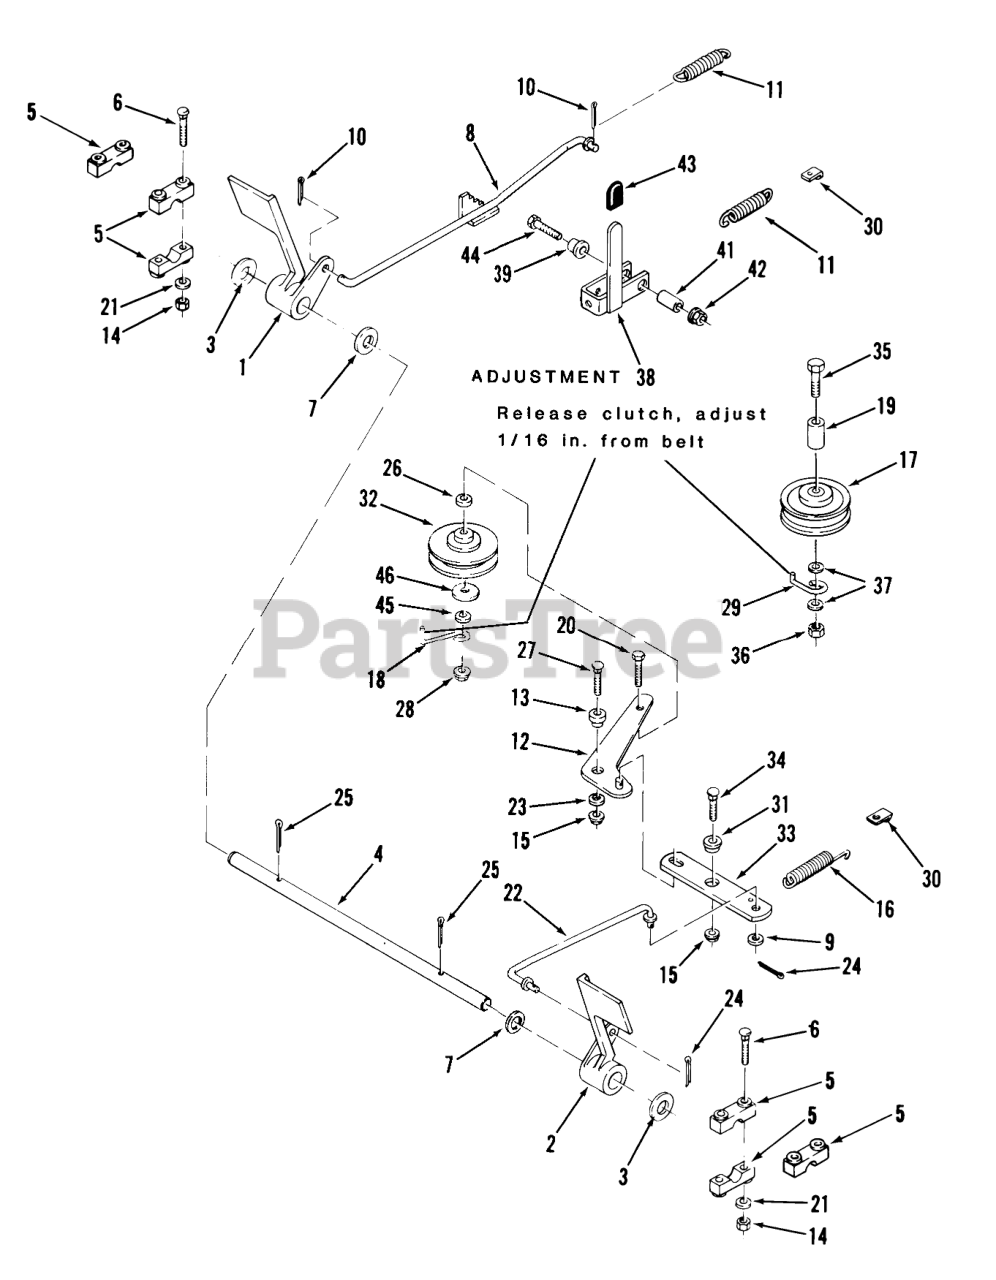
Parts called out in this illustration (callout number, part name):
1	PEDAL-BRAKE R
2	Pedal Clutch
3	Special Washer
4	SHAFT-PEDAL
5	BLOCK PIVOT
6	Washer
7	Washer
8	Assy Brake Rod
9	WASHER 5/16 SAE
10	Pop Rivet
11	SPRING-EXTENSION
12	IDLER ARM ASSY R
13	SPACER-IDLER ARM
14	Nut
15	LOCKNUT-FLANGE
16	SPRING
17	PULLEY-IDLER STATION
18	RETAINER-BELT
19	SPACER
20	Bolt
21	WASHER 5/16 SAE
22	ROD-CLUTCH R
23	Washer
24	Pop Rivet
26	SPACER
27	Carriage Bolt
28	LOCKNUT-FLANGE
29	RETAINER-BELT
30	CLIP - SPRING
31	SPACER
32	IDLER PULLEY
33	BAR-CLUTCH
34	Bolt
35	Bolt 3/8-16 x 3 1/4
36	Nut
37	Washer
38	PAWL-HANDLE ASSY
39	SPACER
41	SPACER
42	LOCKNUT-FLANGE
43	GRIP
44	Bolt
45	Washer
46	WASHER
